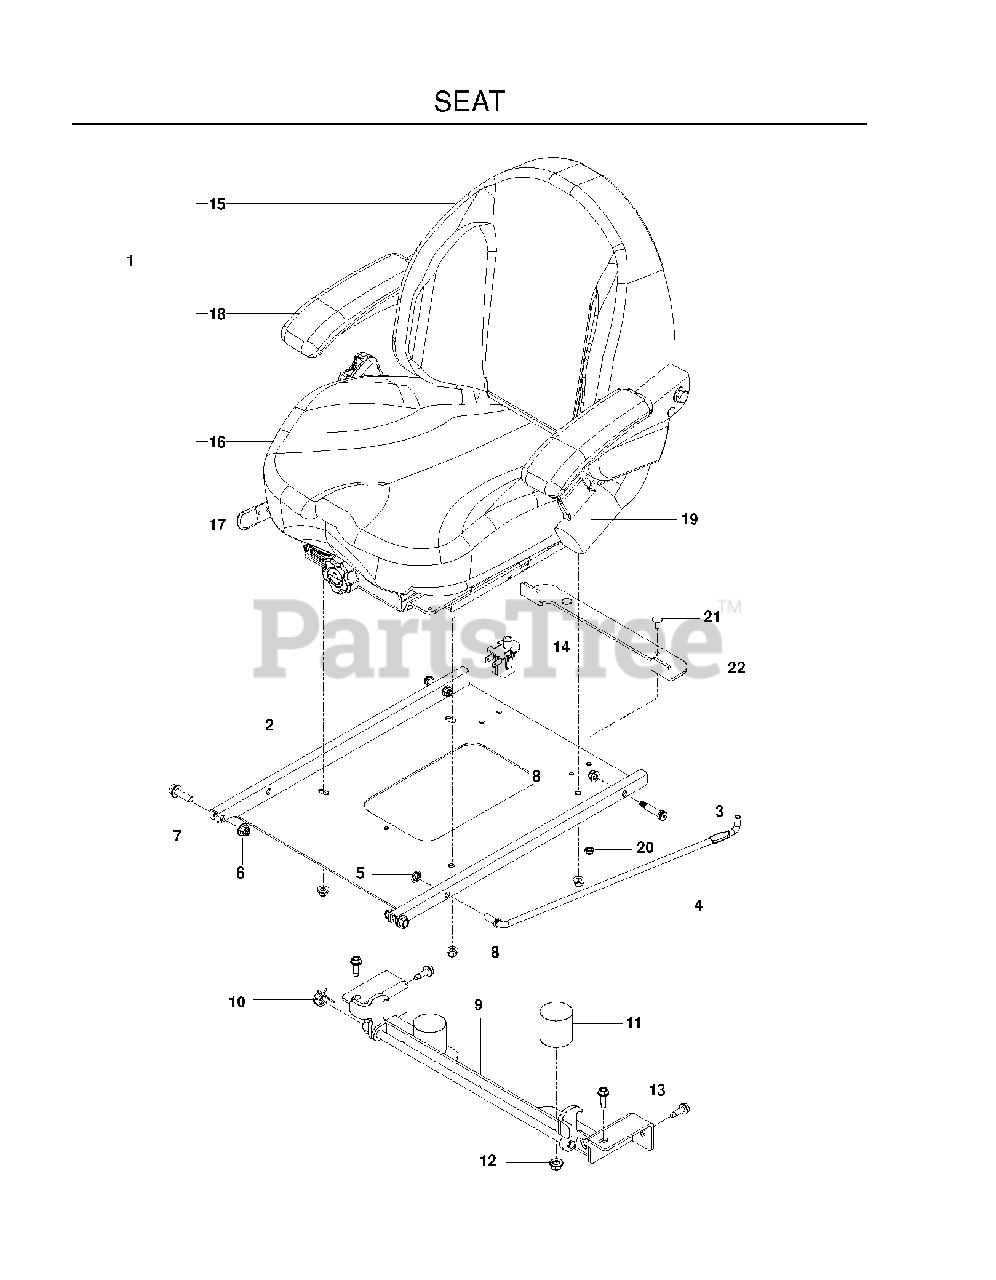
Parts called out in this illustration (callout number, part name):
1	SEAT, 1110 SUSPENSION
2	PAN, SEAT, BLACK
3	BOLT, SHOULDER 3/8 X 1.25
5	NUT 3/8 PALNUT RTNG BLK PHOS
6	NUT 3/8-16 HEX FLG NYLOC ZD
7	HHFS 3/8-16 X 1.25 GD 5
8	5/16-18 NYLOC FLANGE NUT
9	LATCH.SEAT.BLACK
10	SPRING, TORSION
11	BUMPER, RUBBER
12	NUT 3/8-16 HEX FLG NYLOC ZD
13	RP BLT 5/16-18 X 1 THRD FORM D
14	SEAT SWITCH
15	COVER, BACK
16	COVER KIT, CUSHION
17	TRACK KIT
18	ARMREST, LT
19	Seat Belt, Retractable
20	JAM NUT 1/4C (2 2 PW01)
21	RHSSNB, 1/4-20X5/8
22	STOP, SEAT, BLK
